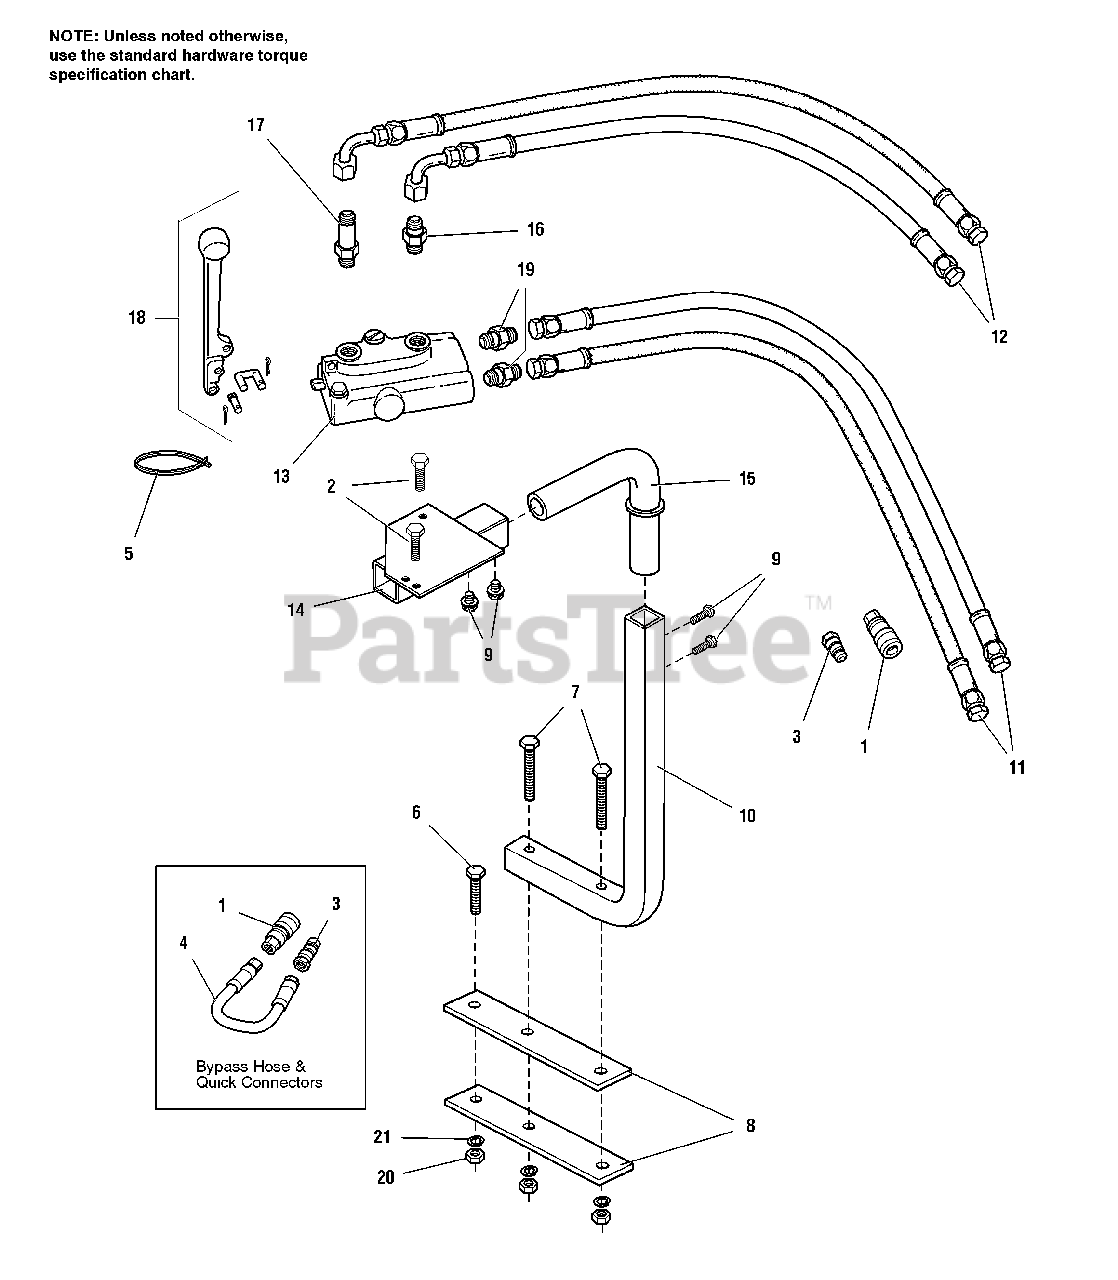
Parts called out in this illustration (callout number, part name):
1	QUICK CONNECTOR, Female Nose Piece Assembly
2	CAPSCREW, Hex Washer Hd, Taptite, 1/4-20 X 1-3/4
3	QUICK CONNECTOR, Male Nose Piece Assembly
4	HOSE, Hydraulic, 1/2" x 11"
5	TIE, Self-Locking
6	CAPSCREW, Hex Hd, 1/2-13 X 3-1/2
7	CAPSCREW, Hex Hd, 1/2-13 x 5, Gr 8
8	PLATE, Clamp, 5/16
9	CAPSCREW, Hex Hd, 5/16-18 X 3/4
10	TOWER ASSEMBLY
11	HOSE, Hydraulic, 23/32" x 40"
12	HOSE, Hydraulic, 1/2" x 75"
13	CONTROL VALVE, Single Spool (From Tractor)
14	PLATE ASSEMBLY, Control Valve Mounting
15	TUBE ASSEMBLY, Control Tower Pivot
16	FITTING, Tube, Male, Short
17	FITTING, Tube, Male, Tall
18	KIT, Control Lever & Pin
19	FITTING, Tube, Male
20	NUT, Hex, 1/2-13
21	WASHER, Lock, 1/2
